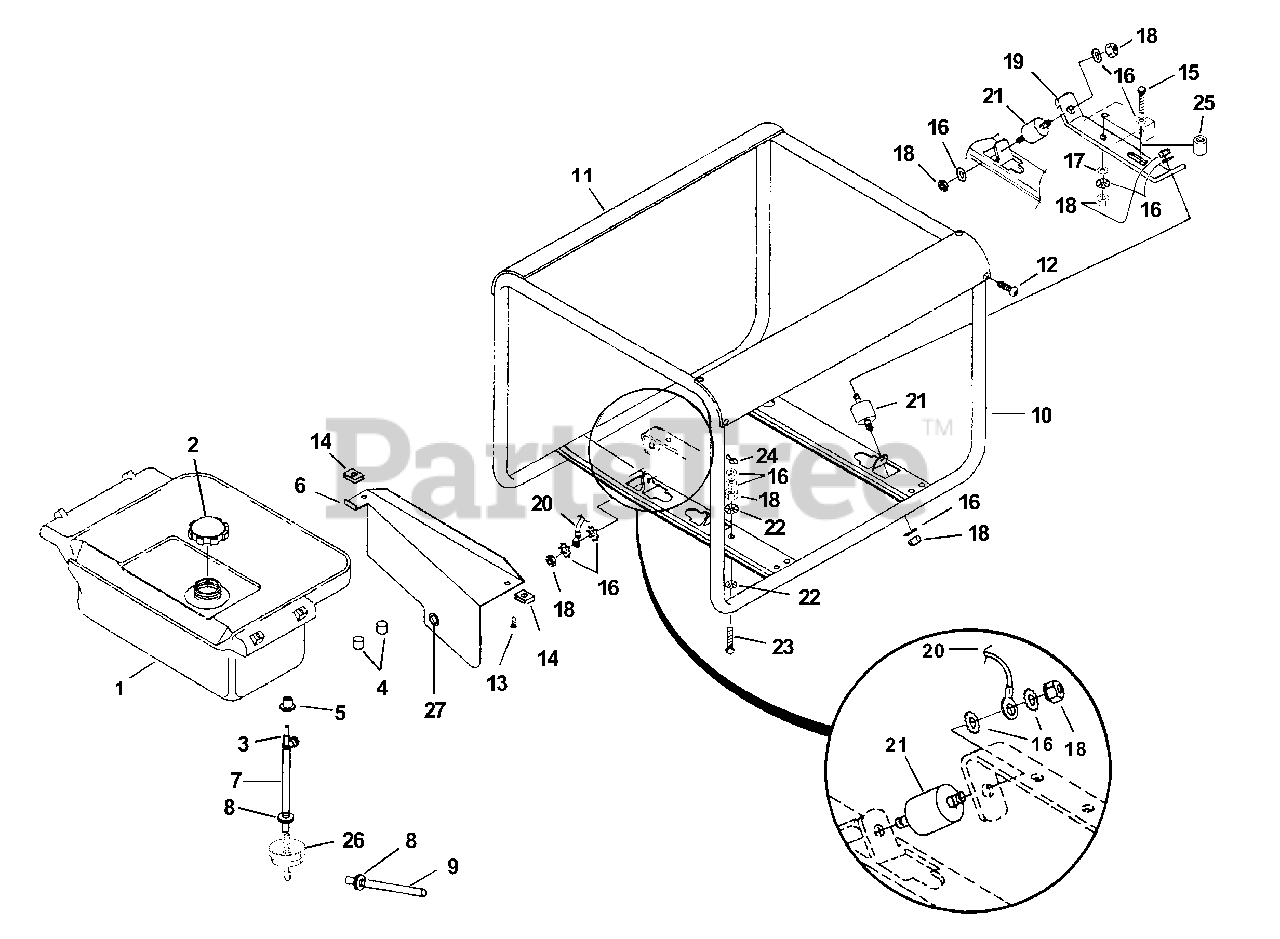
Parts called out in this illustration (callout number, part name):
1	Fuel Tank (5 Gal.)
2	Fuel Cap (2 1/4" dia.)
3	Valve-Fuel
4	Pad-Fuel Tank
5	Bushing
6	Shield-Fuel Tank
7	Fuel Line
8	Clip-Hose
9	Fuel Line to Engine
10	Roll Cage
11	Brace-Tank Support
12	Screw-Torx (10-24 X 1/2")
13	Screw-Pan Hd. (8-32 X 3/8")
14	Nut-Hi Speed
15	Screw-Hex Hd. (5/16-18 X 2 1/4")
16	Washer-Lock (int.)
17	Washer-Flat
18	Nut-Hex (5/16-18)
19	Support-Engine
20	Ground Strap
21	Isolator
22	Washer-Lock-3/8" (ext./int.)
23	Screw-Hex Hd. (5/16-18 X 1 1/2")
24	Nut-Wing
26	Fuel Filter
27	Bushing Snap-In
